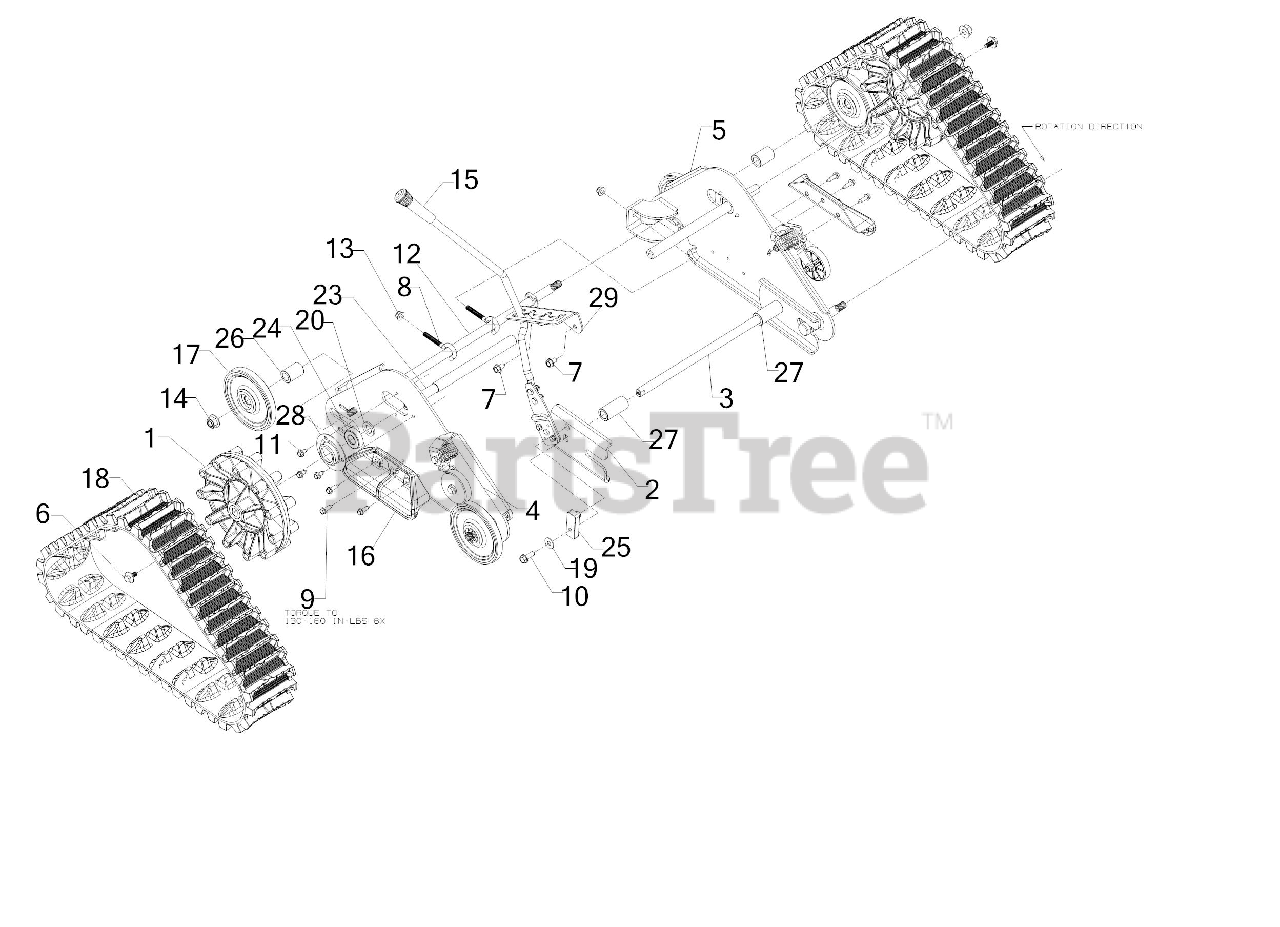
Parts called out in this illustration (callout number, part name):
1	TRACK DRIVE WHEEL
2	HEIGHT ADJUSTMENT LEVER ASSEMBLY
3	HEIGHT ADJUSTMENT ROD ASSEMBLY
4	TRACK ASSEMBLY (RH/FRT)
5	TRACK ASSEMBLY (LH/FRT)
6	SCREW 5/16-24 x .750 GR5
7	SCREW 5/16-18 x .625
8	EYE BOLT 5/16-18 x 2.675
9	SCREW-TT 1/4-20 x .875
10	SCREW 5/16-18 x .875 GR5
11	SCREW 1/4-20X.625
12	REAR WHEEL AXLE
13	FLANGE LOCK NUT 5/16-18
16	TRACK SKID
17	WHEEL-5.00 OD BB
18	DRIVE TRACK 61MM x 22 PITCHES
19	BELL WASHER .337 X.867 x .057
20	FLAT WASHER
23	AXLE-.75 OD x 11.06
24	BALL BEARING
25	HEIGHT ADJUSTMENT ADAPTER
26	SPACER
27	SPACER
28	BEARING CUP
29	HEIGHT ADJUSTMENT BRACKET
